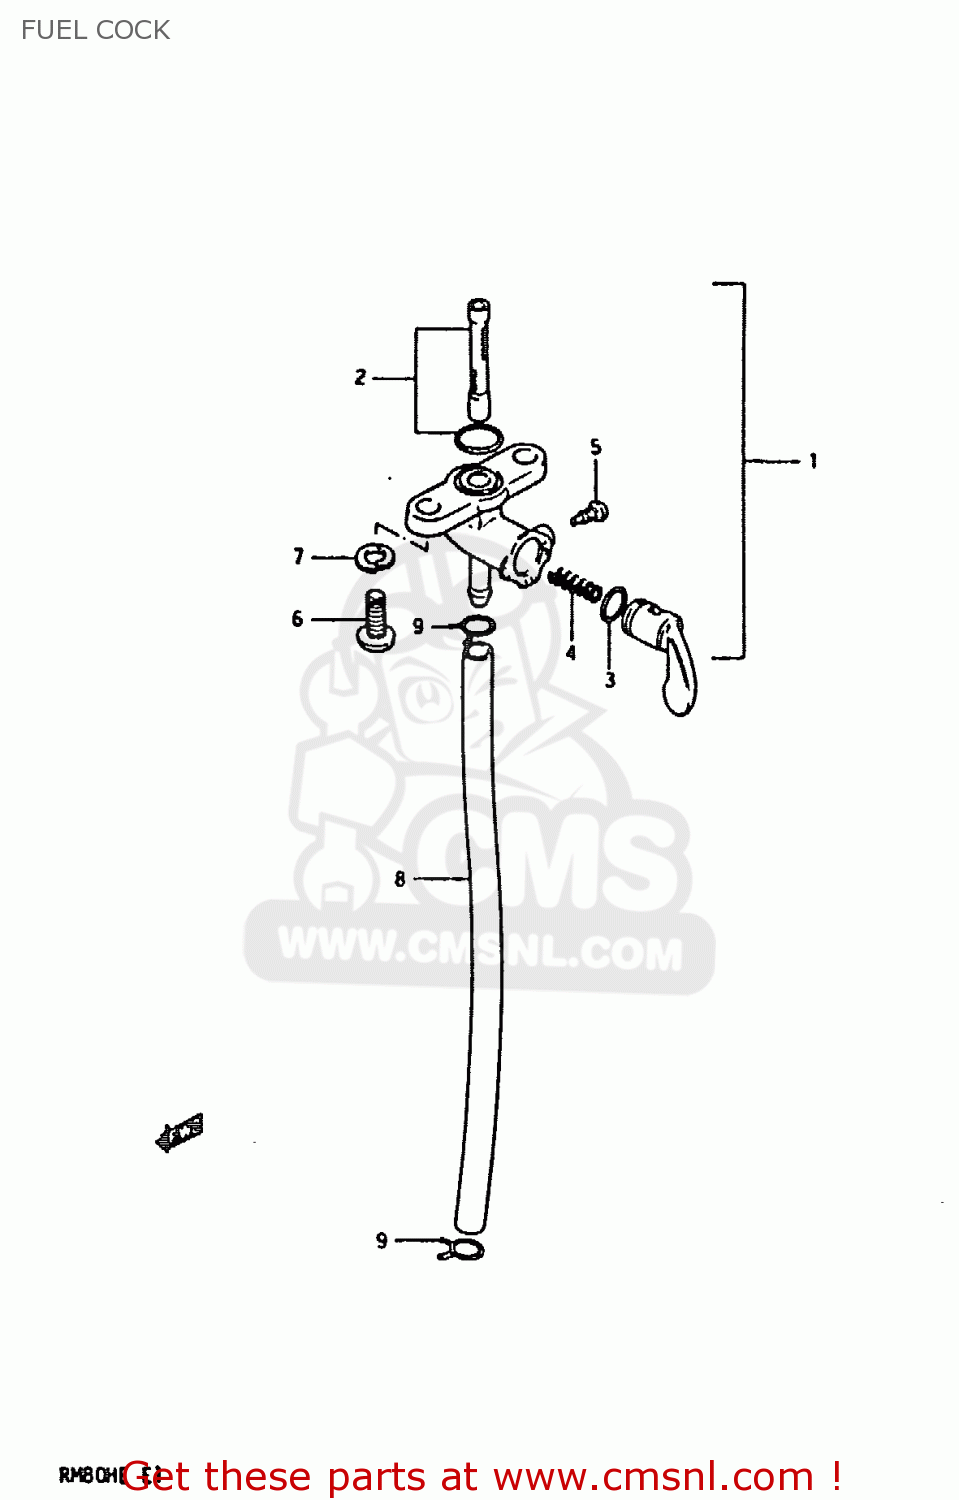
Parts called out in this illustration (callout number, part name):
1	COCK ASSY,FUEL
2	FILTER SET FUEL
3	O RING,LEVER
4	SPRING,FUEL COCK VALUE
5	SCREW
6	SCREW
7	LOCK WASHER
8	HOSE
9	CLIP
